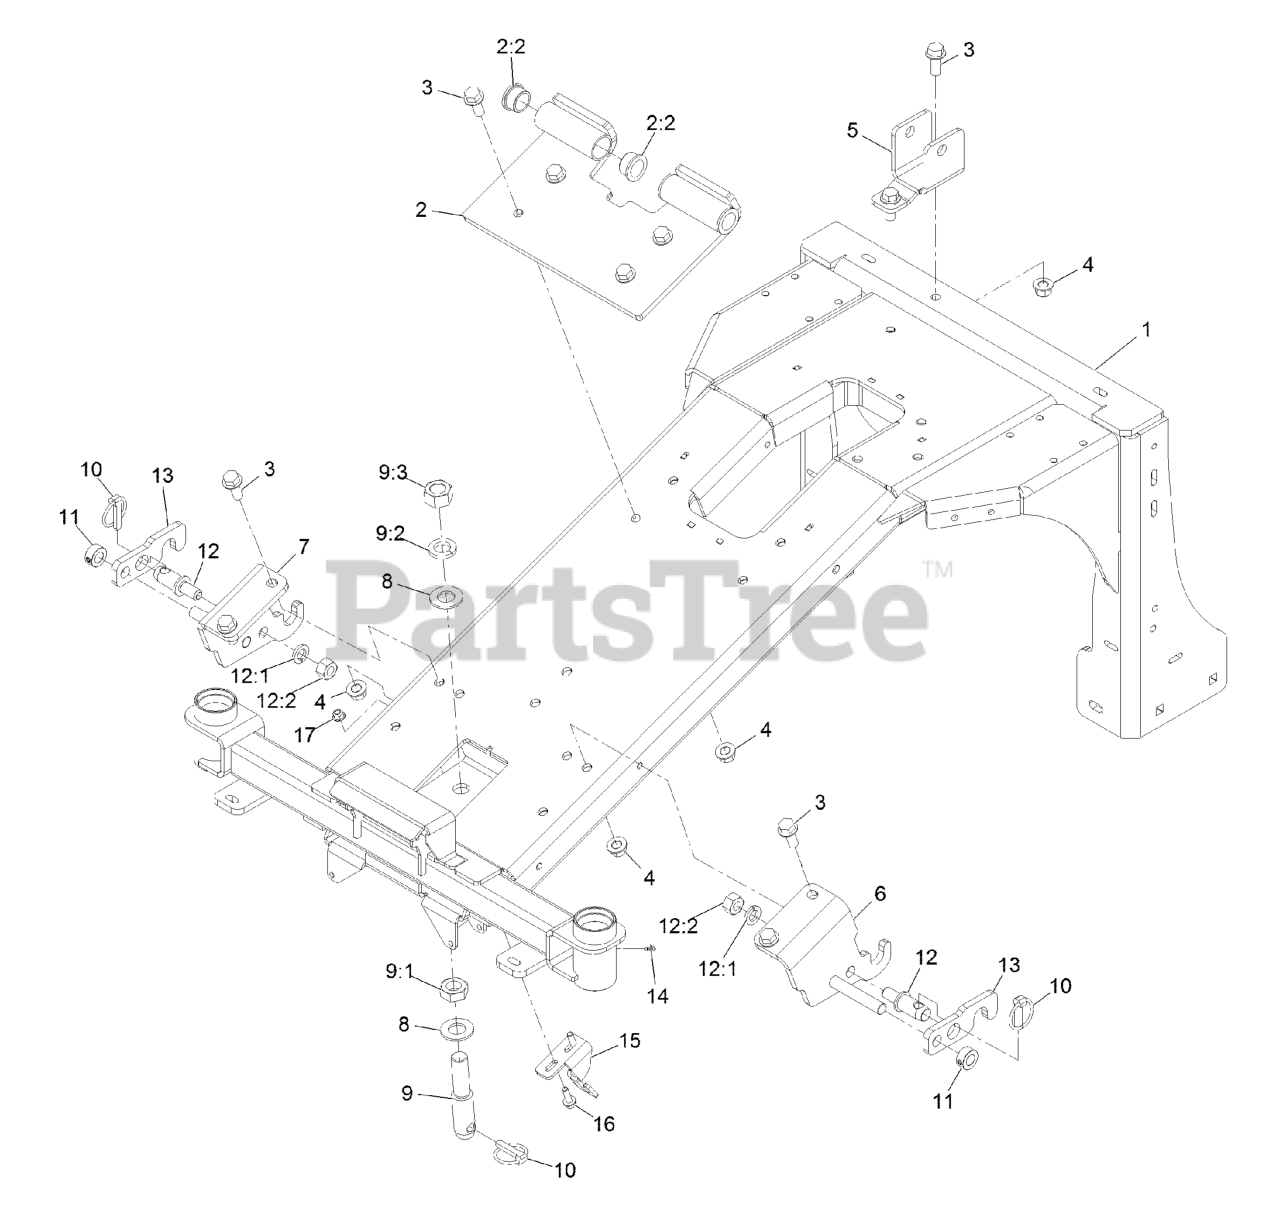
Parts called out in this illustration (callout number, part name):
1	FRONT FRAME ASM
2	PIVOT-ARM, LIFT ASM
2:2	BUSHING-FLANGE
3	SCREW-HHF
4	Nut-Lock 1/2-13
5	BRACKET-MOUNT, CYLINDER
6	X-REF 135-9471-05
7	HITCH PIN-RH
8	WASHER-FLAT
9	1-1/8 X 5-1/4 LIFT ARM PI
9:1	NUT-JAM
9:2	WASHER-LOCK/SP
9:3	NUT-HEX
10	PIN-LYNCH
11	5/8 SHAFT COLLAR
12	7/8 X 3-1/8 ANCHOR PIN (2
12:1	WASHER-LOCK
12:2	NUT-HEX
13	PLATE-ATTACHMENT, LOCK
14	FITTING-GREASE, ZERK
15	BRACKET-CABLE, LCS
16	SCREW-HH
17	NUT-HF, NI
